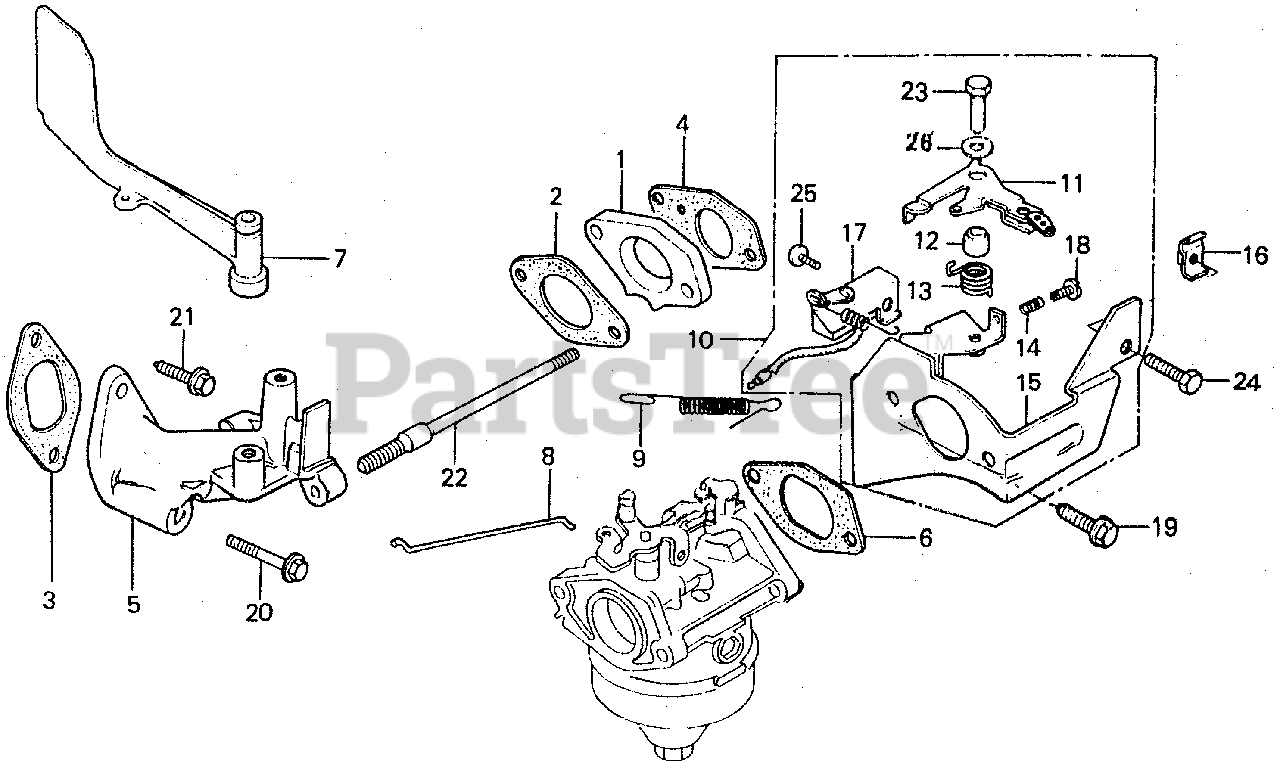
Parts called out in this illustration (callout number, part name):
1	INSULATOR, CARBURETOR
2	GASKET, INSULATOR
3	GASKET, MANIFOLD (NOT AVAILABLE)
4	GASKET, CARBURETOR
5	MANIFOLD, IN. (NOT AVAILABLE)
6	GASKET, AIR CLEANER
7	FLUTTER, GOVERNOR (NOT AVAILABLE)
8	ROD, GOVERNOR (NOT AVAILABLE)
9	SPRING, GOVERNOR
10	CONTROL ASSY.
11	LEVER, CONTROL
12	COLLAR, LEVER SETTING
13	SPRING, RETURN
14	SPRING, STOPPER LEVER
15	STAY, CLEANER CASE
16	HOLDER, WIRE
17	SWITCH ASSY., ENGINE STOP
18	BOLT (4X20) (NOT AVAILABLE)
19	BOLT, FLANGE (6X12) (CT200)
20	BOLT, FLANGE (6X50)
21	BOLT, FLANGE (6X20) (CT200)
22	BOLT, STUD (6X141) (NOT AVAILABLE)
23	BOLT, HEX. (5X20)
24	BOLT, HEX. (6X14)
25	SCREW, PAN (4X8)
26	WASHER, PLAIN (5MM)
